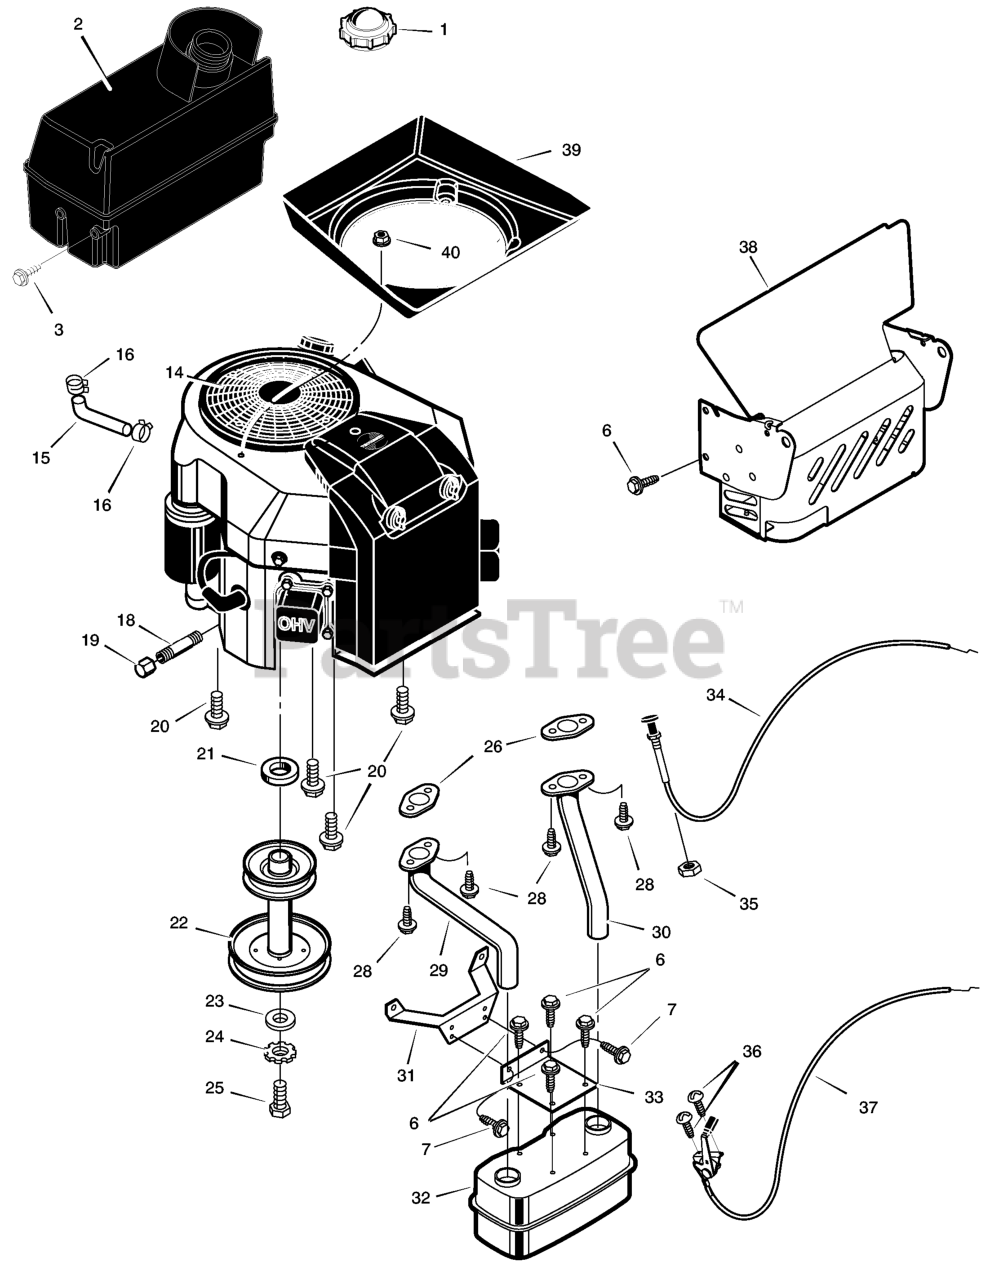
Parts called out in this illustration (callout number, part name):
1	Cap, Fuel
2	Tank, Fuel
14	Engine *
15	Fuel Line (Must cut to length)
16	Clamp
18	Pipe, Oil Drain
19	Cap, Oil Drain
20	Bolt
22	Pulley, Stack
24	Lockwasher
29	Tube, Right Exhaust
30	Tube, Left Exhaust
31	Bracket, Muffler Mount
32	Muffler
33	Bracket, Muffler
35	Nut
37	Control, Throttle
38	Shield Assembly, Heat
40	Screw
